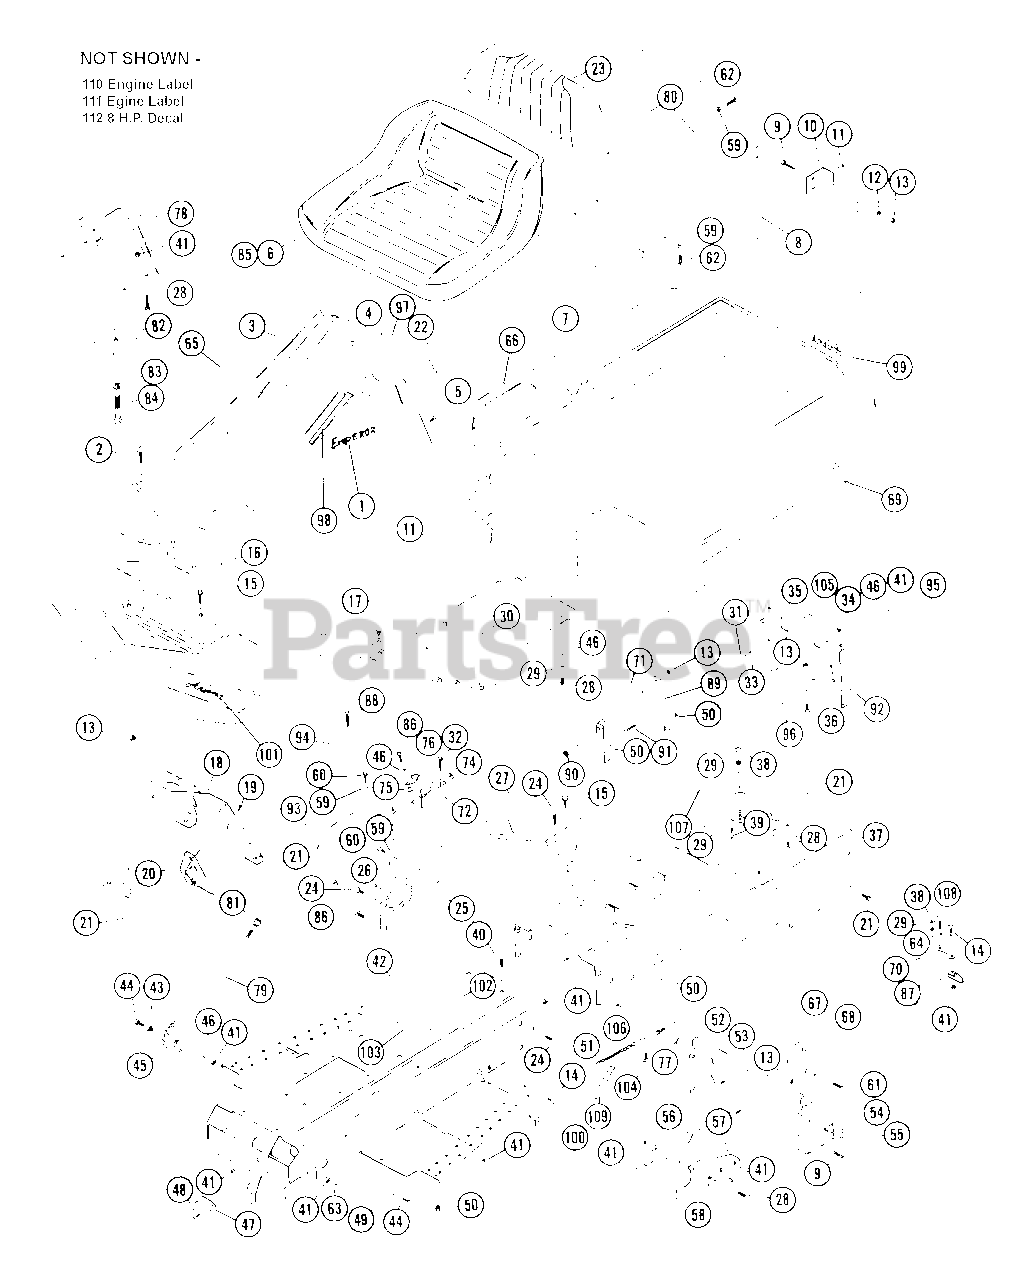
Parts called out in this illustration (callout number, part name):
1	EMPEROR NAME PLATE
2	SCR-MCH .25-20X.63 CRPH PL
4	DASH COVER ASSY.
5	SCR-TAP 10-12X.50 CRPH PL A
6	SEAT
7	ENGINE COVER ASSEMBLY
8	SERVICE BAR
9	BLT-HEX .25-20X1.50 PL GR5
10	BRACKET
11	RVT-POP .187X.402 DOME ST
12	WSHR-FL-STL.312X.734X.065PL
13	NUT-LK-CTR .250-20 PL
14	BLT-HEX .31-18X.50 PL GR2
15	BLT-SERHFWH .25-20X.50 PL
16	FRONT WHEEL COVERS
17	SCR-SLTR-SERNK .25-20X.62 PL
18	CONTROL PANEL
19	SCR-TAP 10-24X.375 CRPH 1A
20	THROTTLE CONTROL
21	BLT-SERHFWH .31-18X.50 PL
23	SEAT BACK
24	BLT-RDHDSQSHNK .31-18X.50 YZ
25	SHIFT QUADRANT
26	CLIP
27	SEAT HINGE
28	BLT-HEX .31-18X.75 PL GR2
28	BLT-HEX .31-18X1.50 PL GR2
29	WSHR-LK .312X.097 PL HVY
30	BRACKET
31	SCR-TAP 10-16X1.0 SLHP PL AB
32	SCR-TAP 10-24X.375 CRPH 1A
33	WSHR-FL-STL .250X.562X.049 PL
34	BUMPER GROMMET
35	LEG
36	BLT-HEX .25-20X.50 PL GR2
37	FRAME
38	NUT-HEX .312-18
39	BLT-HEX .31-18X1.25 PL GR2
40	BLT-RDHDSQNK .75-10X3.0
41	NUT-LK .312-18 GR A PL
42	FRONT FRAME ASSY.
43	SPACER -SHLD .344X.500X.469
44	BLT-HEX .31-18X1.00 PL GR 2
45	BRAKE LATCH
46	WSHR-FL-STL .38X.875X.083 PL
47	LOCK SPRING
48	SCR-TAP 10-12X.50 CRPH PL A
49	SPACER .344X1.000X.375
50	NUT-LK-FLG .250-20 PL
51	BRAKE CHAIN
52	BRACKET
54	PIN-HAIR INT .09X1.88 PL
56	WSHR-FL-STL .323X.625X.062 PL
57	BELT FINGER
58	BELT FINGER BRACE
59	WSHR-LK .250X.077 HVY PL
60	BLT-HEX .25-20X.50 PL GR2
61	SCR-TAP 8-32X.38 SL HWH PL 23
62	BLT-HEX .25-20X.75 PL GR2
63	WSHR-FL-STL .323X.625X.062 PL
64	WSHR-LK .375X.115 HVY PL
65	MOWER HEIGHT DECAL
66	SHIFT DECAL
67	GASKET
68	PIPE
68	EXHAUST PIPE
69	SHROUD DECAL
70	MUFFLER BRACKET
71	SHIELD
72	SWITCH HOUSING
74	GROMMET, .31 ID
75	BSHG, FLG .325X.499X.26X.88
76	CAM NO SCRAP
77	BLT-SERHFWH .25-20X.50 PL
78	SEAT BRACKET
79	PARKING BRAKE ROD
80	SEAT BRACE
82	SEAT SUPPORT WASHER
83	WSHR-LK .500X.151 HVY PL
84	BLT-HEX .50-13X1.25 PL GR2
85	SEAT
86	BLT-SERHFWH .31-18X.75 PL
88	SCR-TAP 12-14X1.25 CROVH PL 1A
89	BRACE
90	GROMMET, .31 ID
91	BLT-HEX .25-20X.38 PL GR2
92	NUT-LK-CTR .250-20 PL
93	SHIFT PANEL
95	BAFFLE
96	BLT-HEX .31-18X.75 PL GR2
97	DASH DECAL
98	MOWER CLUTCH DECAL
99	DECAL
101	ARIENS NAME PLATE
102	CAUTION DECAL
103	PATENTS PENDING LABEL
104	BLT-RDHDSQNK .25-20X.62 PL
105	CLAMP
106	BRACKET
107	WSHR-FL-STL .328X.875X.062 PL
108	BLT-HEX .38-16X.75 PL GR2
109	SG-TENS .041X.35X2.11 WLD 8
110	ENGINE LABEL
111	ENGINE LABEL
